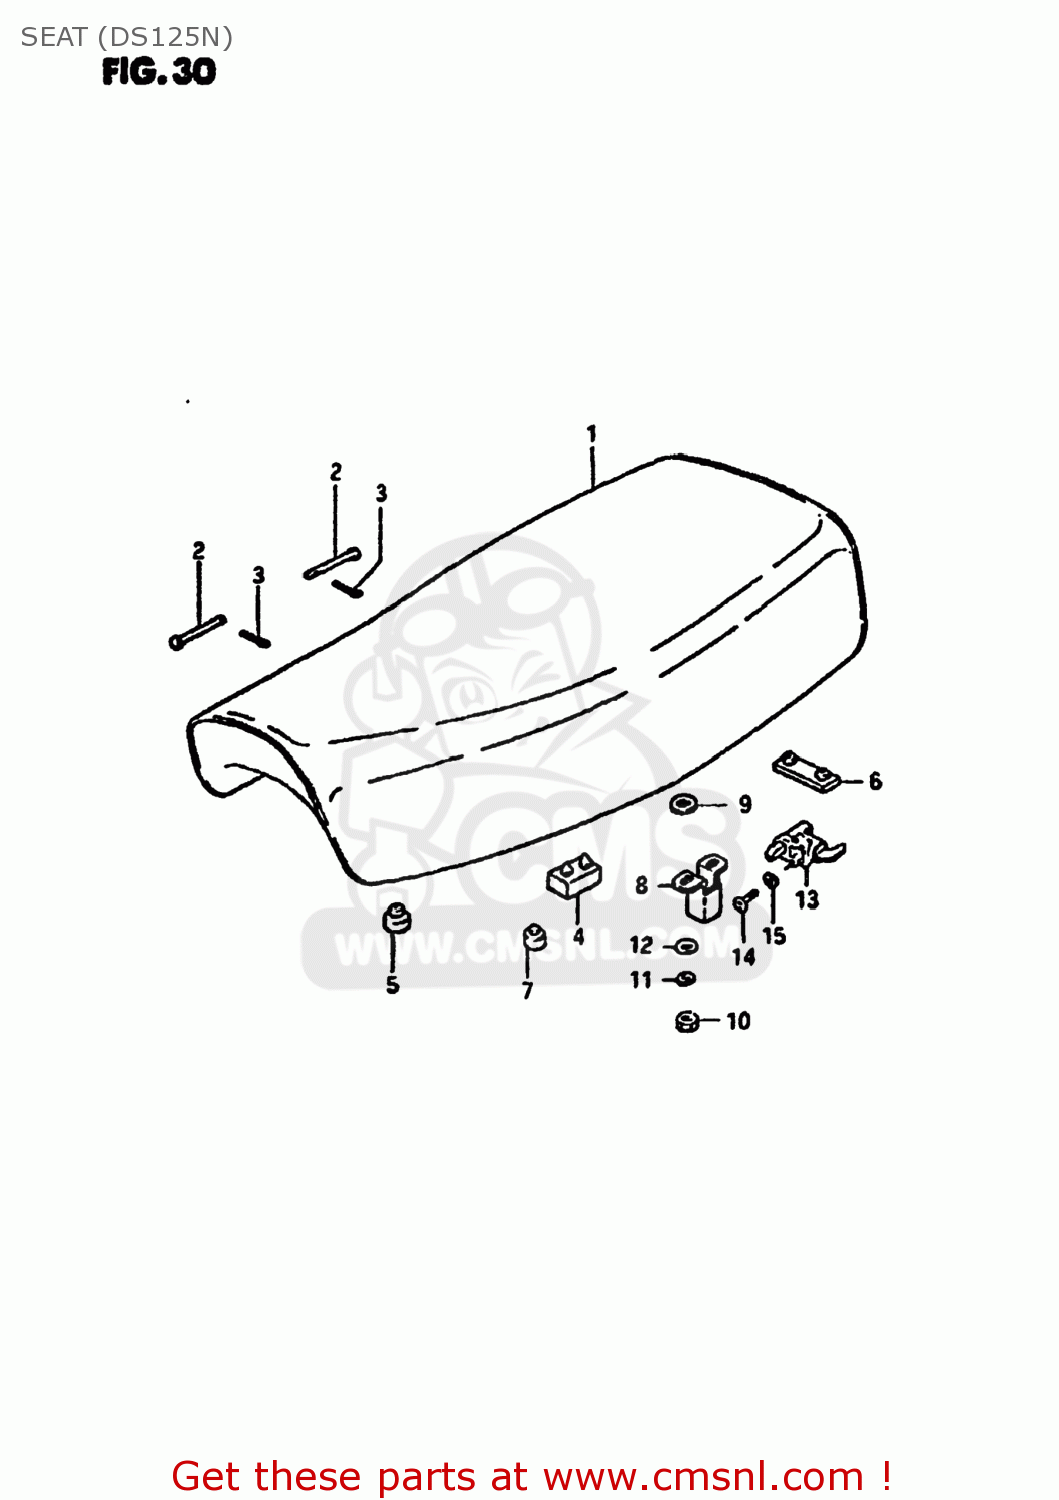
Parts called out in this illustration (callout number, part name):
1	SEAT ASSEMBLY
2	PIN
3	PIN
4	CUSHION
5	CUSHION(11.5X22X20)
6	CUSHION
7	CUSHION
8	PLATE,CLAMP GUIDE
9	WASHER(8.5X18X1)
10	NUT
11	LOCK WASHER
12	WASHER
13	LOCK ASSEMBLY,SEAT
14	SCREW
15	LOCK WASHER
